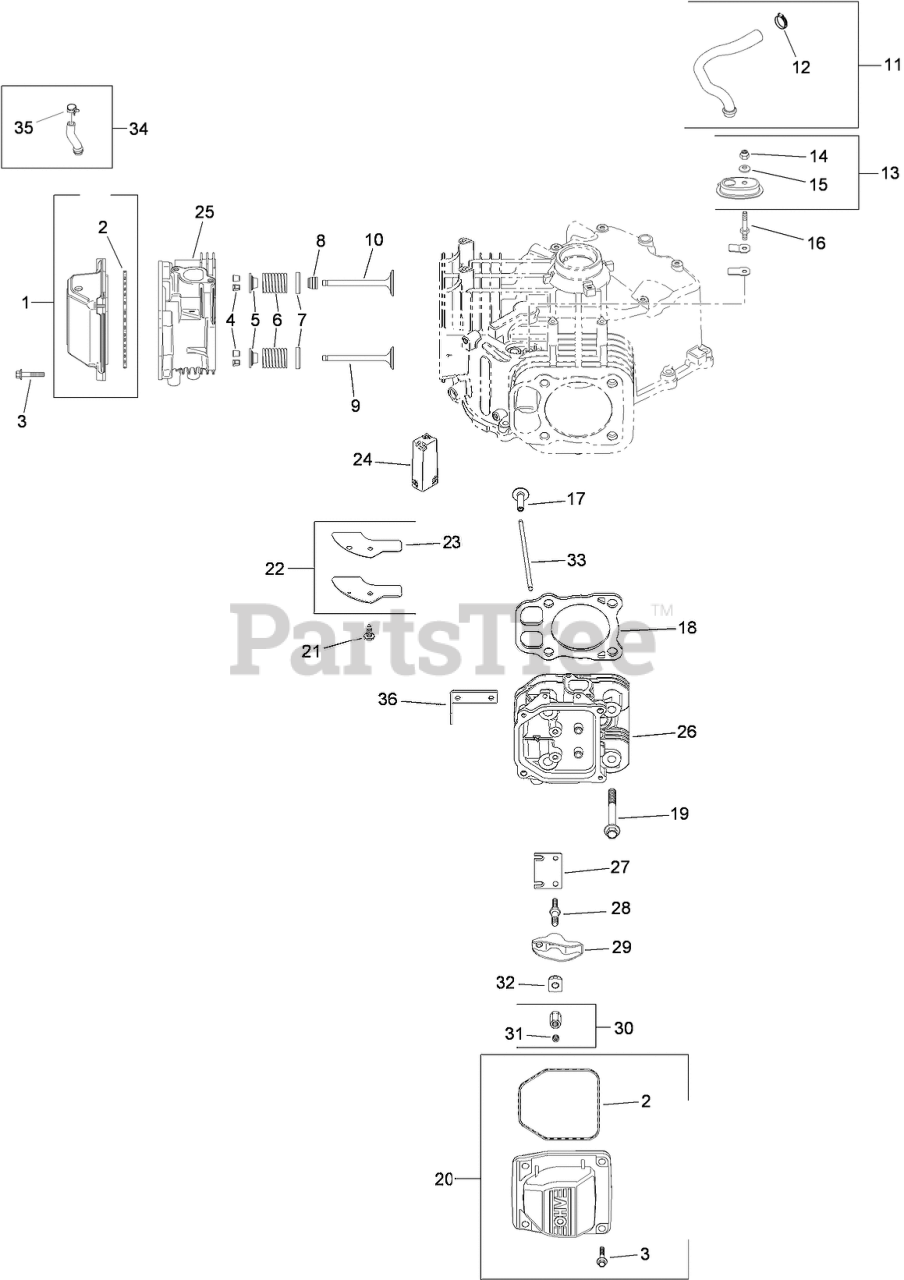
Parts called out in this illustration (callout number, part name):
1	BREATHER VALVE COVER KIT (INCLUDES REF 2)
2	O-RING (VALVE COVER)
3	SCREW-FLANGE (M6X1.0X30)
4	RETAINER KIT
5	CAP-SPRING, VALVE
6	SPRING-VALVE
7	RETAINER-SPRING
8	SEAL-STEM, VALVE
9	VALVE-EXHAUST (STD)
10	VALVE-INTAKE (STD)
11	BREATHER HOSE KIT (INCLUDES REF 12)
12	CLAMP-HOSE, SPRING (1/2)
13	BREATHER HOUSING KIT (INCLUDES REF 14, 15)
14	NUT-LOCK (M5X.8)
15	WASHER-SEALING
16	STUD-COVER, BREATHER
17	TAPPET KIT
18	CYLINDER HEAD GASKET KIT
19	SCREW-FLANGE (M10X1.5X90)
20	PLAIN ROCKER COVER KIT (INCLUDES REF 2, 3)
21	SCREW-FLANGE, THREAD FORMING (M6X1.0X16)
22	BREATHER COVER KIT (INCLUDES REF 23)
23	GASKET-COVER, BREATHER
24	FILTER-BREATHER
25	CYLINDER HEAD NO.1 ASM
26	CYLINDER HEAD NO.2 ASM
27	PLATE-GUIDE
28	STUD-ROCKER
29	ARM-ROCKER
30	HEX NUT ASM (INCLUDES REF 31)
31	SCREW-SET
32	PIVOT-ARM, ROCKER
33	ROD-PUSH
34	FUEL PUMP HOSE W/CLAMP KIT (INCLUDES REF 35)
35	CLAMP-HOSE
36	STRAP-LIFTING
